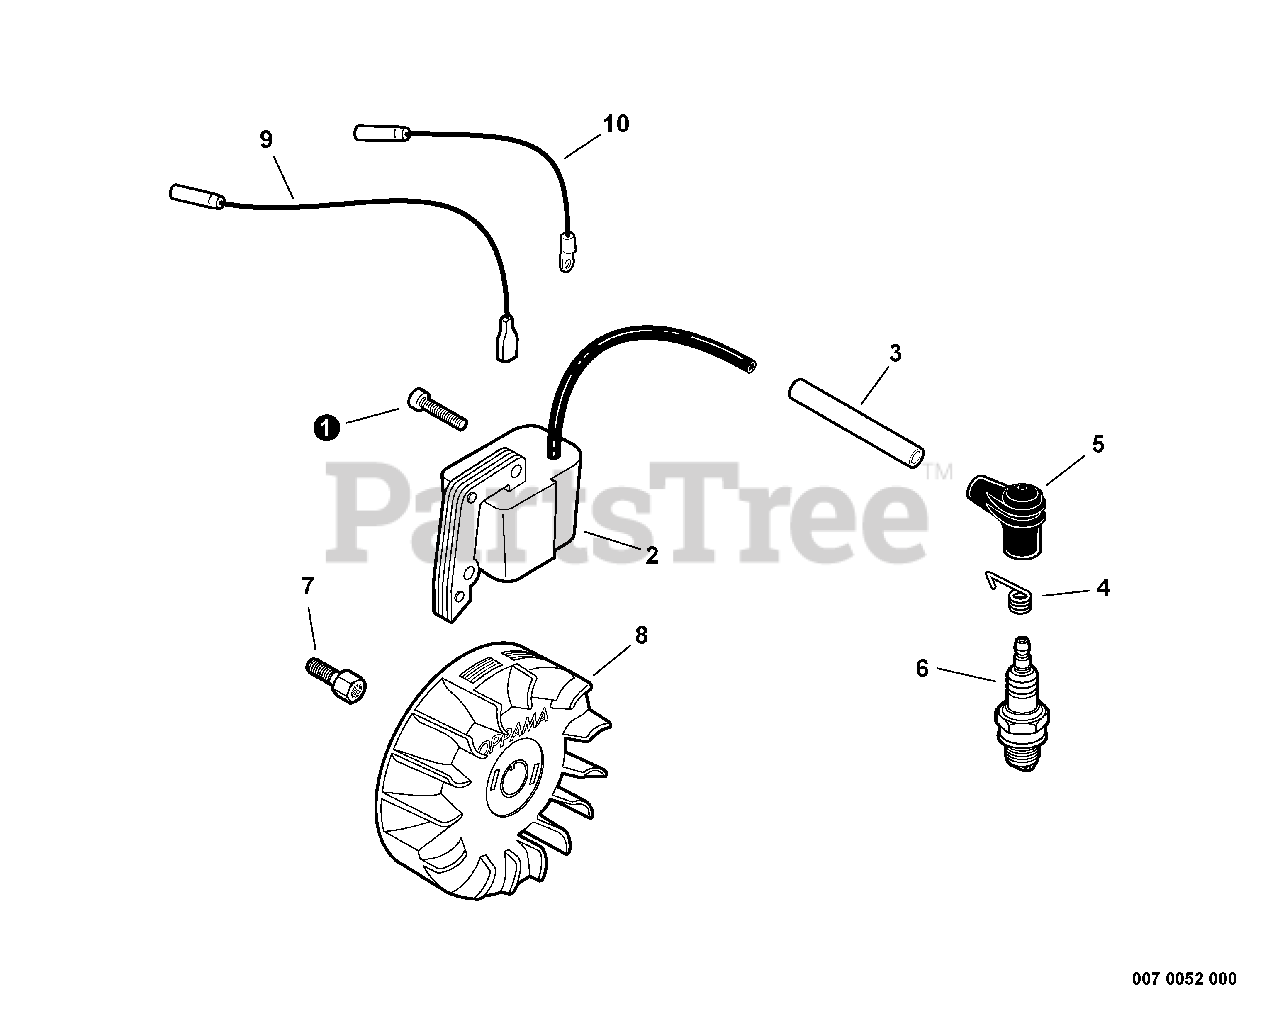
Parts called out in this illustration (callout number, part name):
1	SCREW - 4X22
2	COIL, IGNITION
4	TERMINAL, SPARK PLUG CAP
5	CAP, SPARK PLUG
6	SPARK PLUG -- BPMR-7A
7	HUB, FAN
8	FLYWHEEL
9	LEAD - IGNITION
10	LEAD - GROUND
